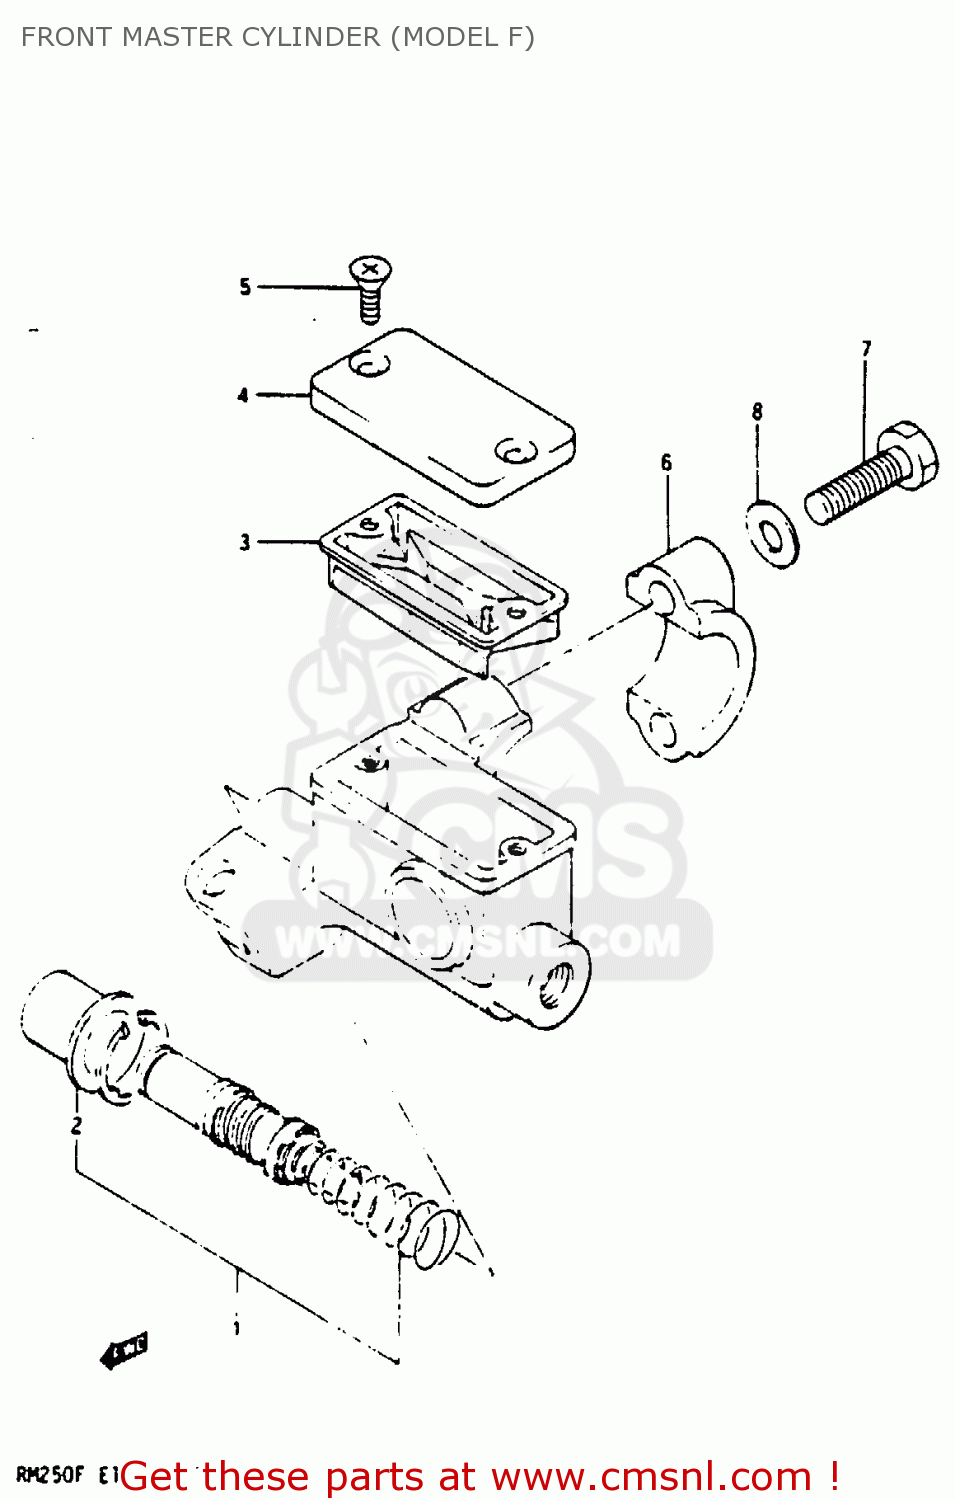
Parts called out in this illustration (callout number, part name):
1	PISTON/CUP SET,FR MASTER
2	BOOT
3	DIAPHRAGM
4	CAP
5	SCREW
6	HOLDER,MASTER CYLINDER
7	BOLT
8	WASHER
